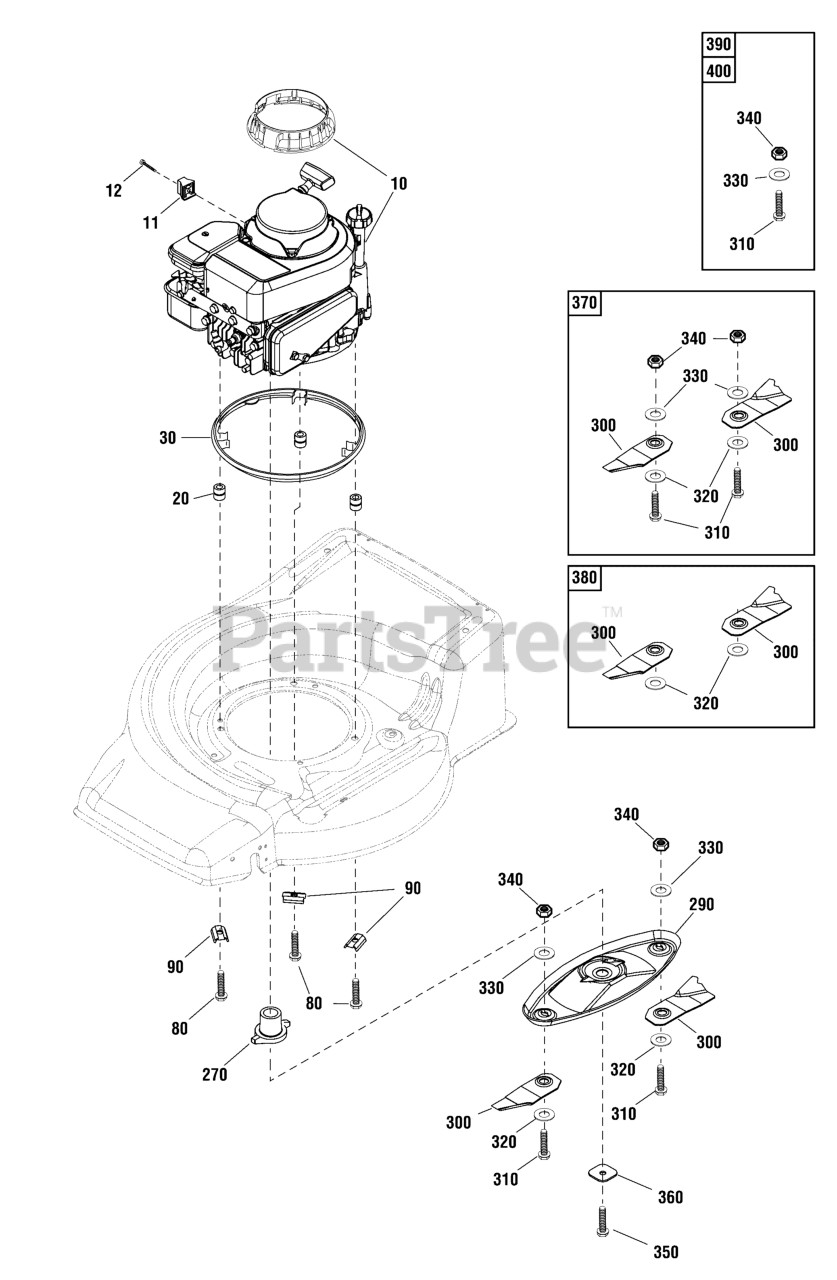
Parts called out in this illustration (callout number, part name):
10	* ENGINE, Briggs & Stratton Series 450
11	SPACER, Throttle Mount
12	SCREW, Hex Head Phillips, 8 x 35
20	SPACER, 20mm
30	SPACER RING
80	BOLT, Taptite, 3/8 UNC x 50
90	SADDLE PLATE
270	SLEEVE, Locking, 4 Stroke
290	BLADE Disc, Oval
300	BLADE, Low Profile
310	BOLT, Blade
320	WASHER, Blade Tension
330	WASHER, Belleville
340	NUT, Nylock, 3/8 UNC
350	BOLT, Blade Disc
360	WASHER, Blade Disc
370	KIT, Blade & Bolt (1 Pair)
380	KIT, Blade & Bolt, Bulk Pack (50 Pairs)
390	KIT, Hardware, Bolt, Washer, Nut (1 Pack)
400	KIT, Hardware, Blade Mounting , Bulk Pack (50 Pair)
